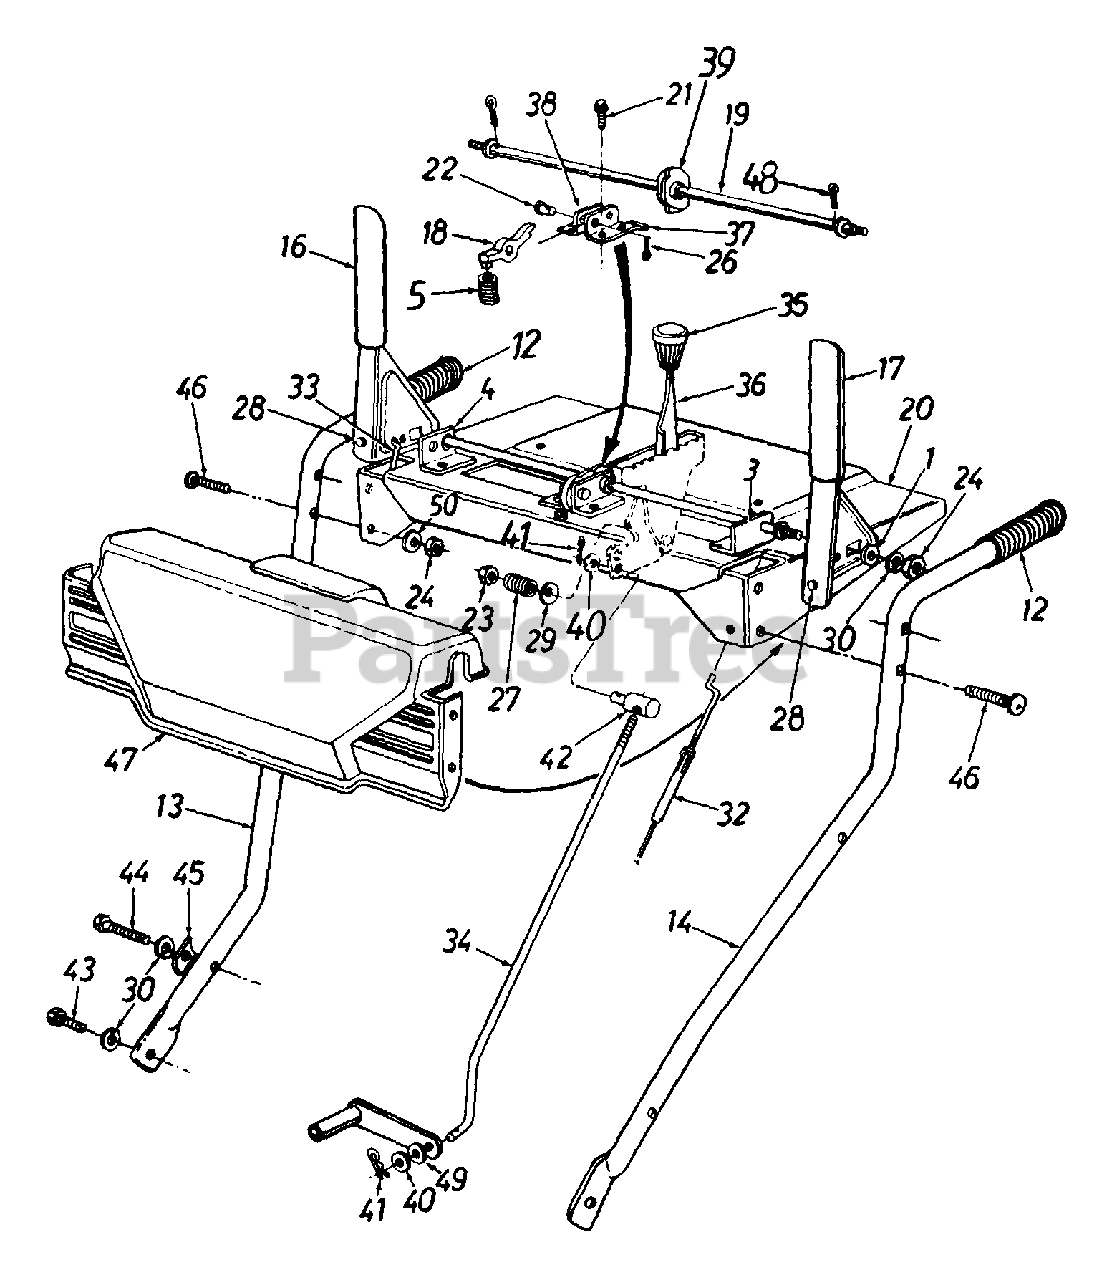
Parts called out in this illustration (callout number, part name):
1	Wash. .72" O.D.
5	Compression Spring
13	Handle - R.H.
14	Handle - L.H.
16	Engagement Handle - R.H.
17	Engagement Handle - L.H.
18	Pawl Handle Lock
19	Rod Cam
22	Clevis Pin .437" Dia. x .65" Lg.
23	Hex Ins. L-Nut 3/8-24 Thd.
24	Hex Nut 5/16-18 Thd.
26	Cotter Pin 3/32" Dia. x 1" Lg.
27	Compression Spring
28	Rubber Bumper
29	Bell-Wash. .38" I.D. x .88" O.D.
30	L-Wash. 5/16" I.D.
32	Auger Clutch Cable
33	Drive Clutch Cable
34	Shift Rod
35	Shift Knob
36	Shift Handle
39	Cam Handle Lock
40	Fl-Wash. .344" I.D. x .62" O.D.
41	Internal Cotter Pin 5/16" Dia.
42	Ferrule
43	Hex Bolt 5/16-18 x .62" Lg.
44	Hex Bolt 5/16-18 x 1.75" Lg. (Gr. 5)
45	Handle Tab
46	Curved Carr. Bolt 5/16-18 x 1.5"
47	Handle Panel
48	Cotter Pin 3/32" Dia. x .75" Lg.
49	Spr. Wash. .32" I.D. x .62" O.D.
50	Bell-Wash. .325" I.D. x .88" O.D.
